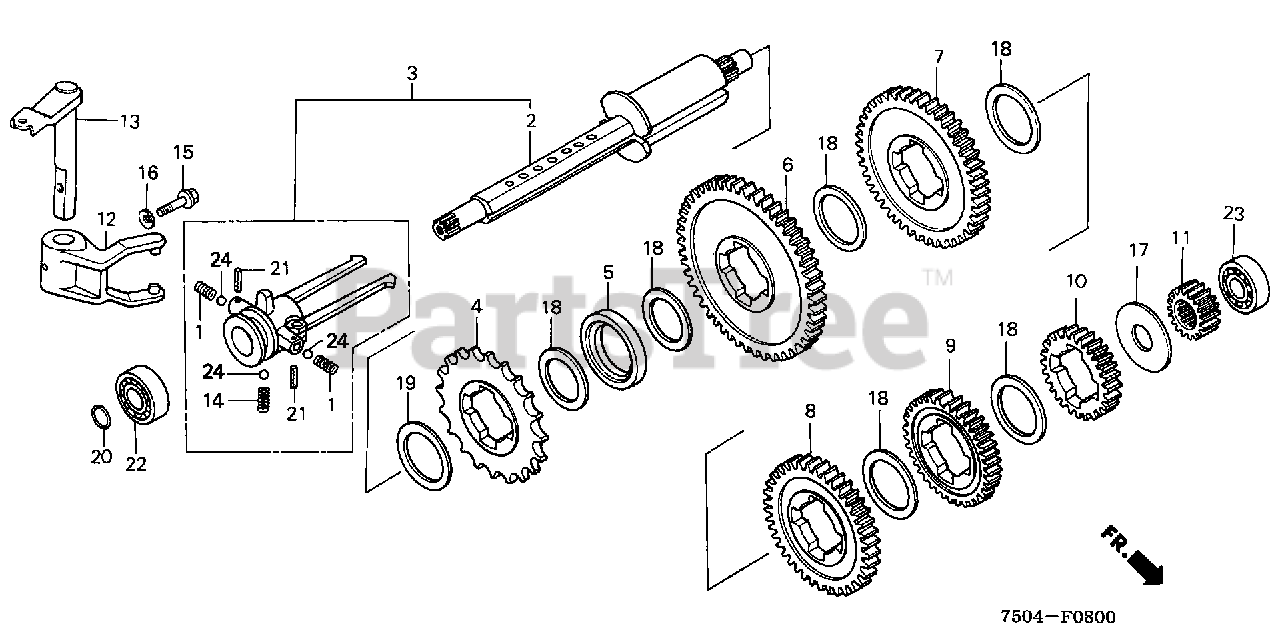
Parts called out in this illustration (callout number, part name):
1	SPRING, CHANGE KEY
2	SHAFT, CHANGE
3	HOLDER ASSY., KEY (NOT AVAILABLE)
4	SPROCKET, REVERSE
5	POSITIONER, NEUTRAL
6	GEAR, CHANGE LOW (56T)
7	GEAR, CHANGE SECOND (53T)
8	GEAR, CHANGE THIRD (48T)
9	GEAR, CHANGE FOURTH (41T)
10	GEAR, CHANGE FIFTH (32T)
11	GEAR, COUNTERSHAFT DRIVE (17T)
13	SHAFT, SHIFTER
14	SPRING, BALL SETTING
15	BOLT, KNOCK (8X23)
16	WASHER, CONICAL SPRING (8MM)
17	WASHER, CHANGE THRUST (20.2MM)
18	WASHER, DISTANCE (2MM)
19	WASHER, DISTANCE (1MM)
20	O-RING (17.8X1.9) (NOK)
21	PIN, SPRING (3X14)
22	BEARING, RADIAL BALL (6004)
23	BEARING, RADIAL BALL (6203)
24	BALL, STEEL (#10) (5/16)
